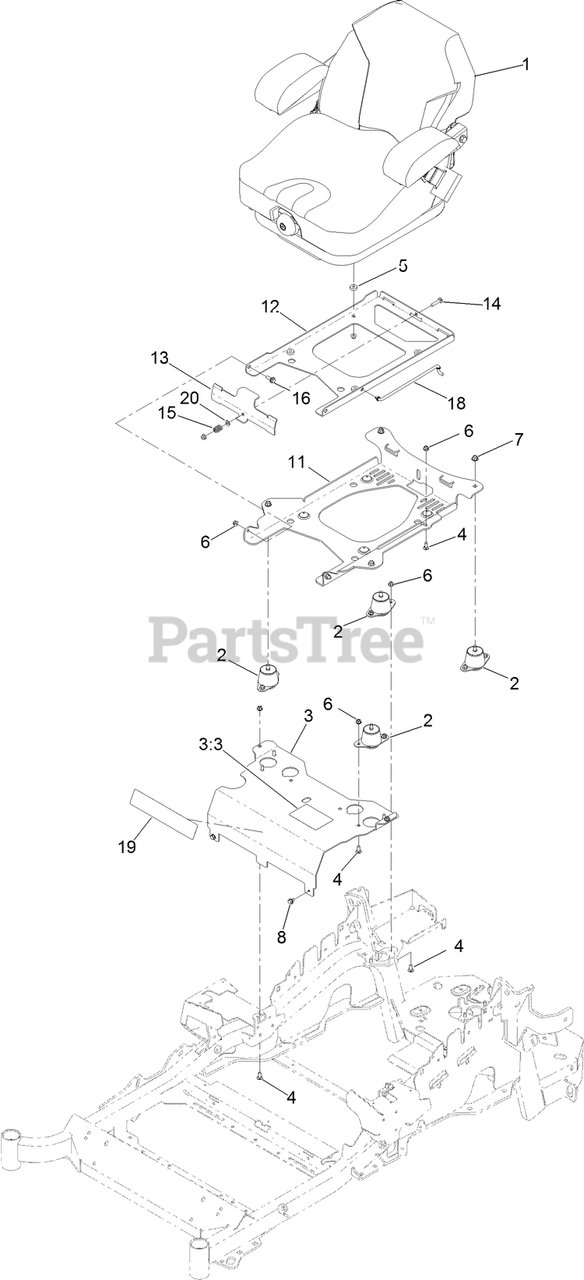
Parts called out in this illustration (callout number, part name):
1	SUSPENSION SEAT ASM
2	ISOLATOR-SEAT
3	SEAT MOUNT ASM
3:3	DECAL-SERVICE AID
4	SCREW-CARR
5	SPACER-PIN, MOUNTING
6	NUT-HF, NI
7	NUT-HF, NI
8	SCREW
11	PLATE-TILT, SEAT SUPPORT
12	PLATE-FRAME, SEAT
13	PLATE-LATCH, SEAT
14	BOLT-CARR
15	SPRING-COMPRESSION
16	SCREW-SHOULDER
18	ROD-PROP
19	DECAL
20	WASHER-PLAIN
